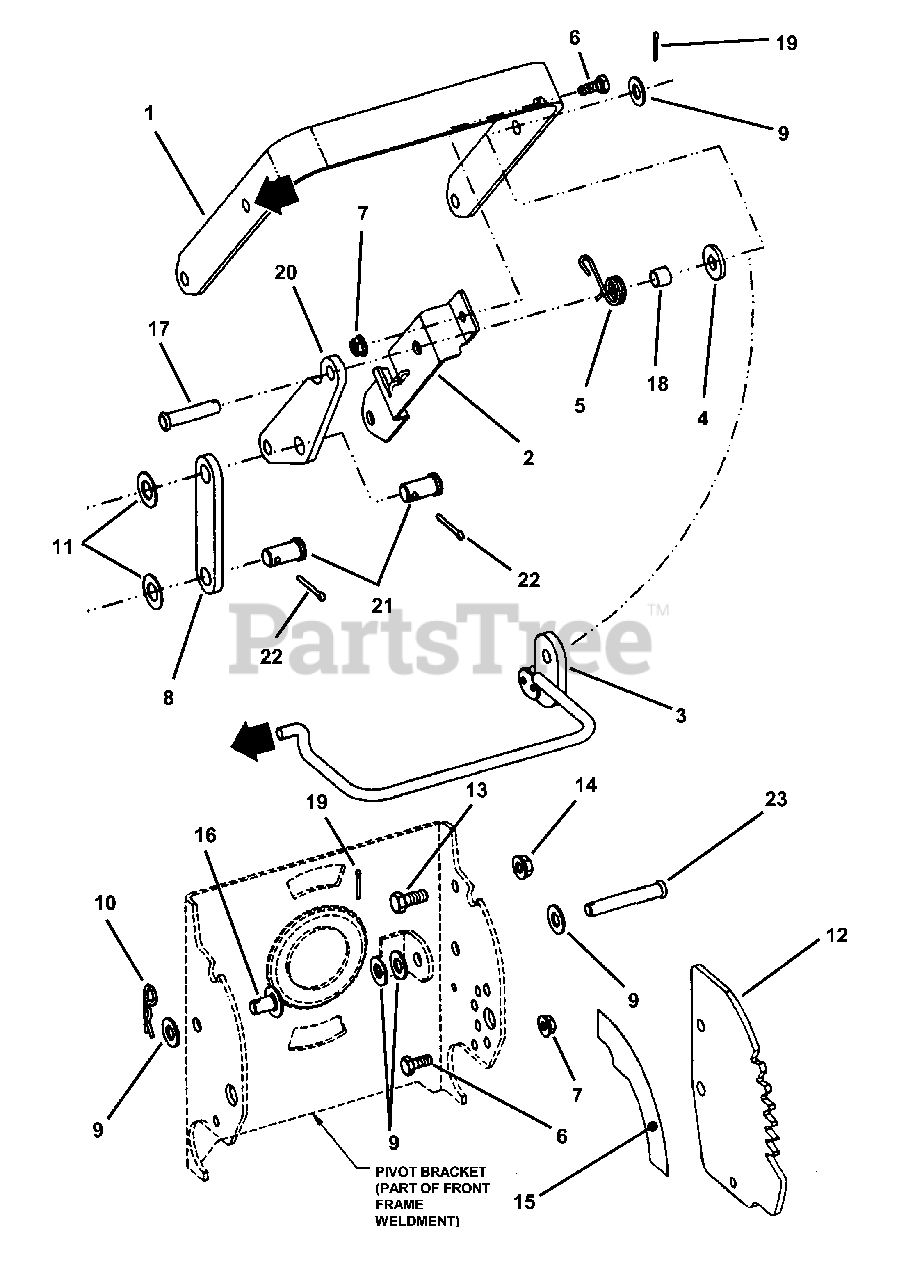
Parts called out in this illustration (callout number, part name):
1	HANDLE, Deck Lift
2	BRACKET, Pivot Support
3	WELDMENT, Deck Lift Handle
4	WASHER, Slipper
5	SPRING, Torsion (Deck Position)
6	SCREW, 1/4-20 x 5/8" Hex Head Cap, Grade 5
7	NUT, 1/4-20 Hex Flange Lock
8	LINK, Connector
9	WASHER, 3/8" Flat
10	HAIRPIN, 3/32 x 1-1/2"
11	WASHER, 1/2" Flat
12	DETENT, Lift Handle
13	SCREW, 5/16-18 x 3/4" Hex Cap, Grade 5
14	NUT, 5/16-18 Hex Flange Lock, Grade 5
15	DECAL, Deck Position
16	PIN, 3/8 x 1/2" Expanded Head Clevis
17	PIN, 3/8 x 1-5/8" Clevis
19	PIN, 3/32" x 3/4" Cotter
20	PLATE, Connector Arm
21	PIN, 1/2 x .725 Clevis
22	PIN, 1/8 x 1" Clevis
23	PIN, Clevis, 3/8 x 2"
